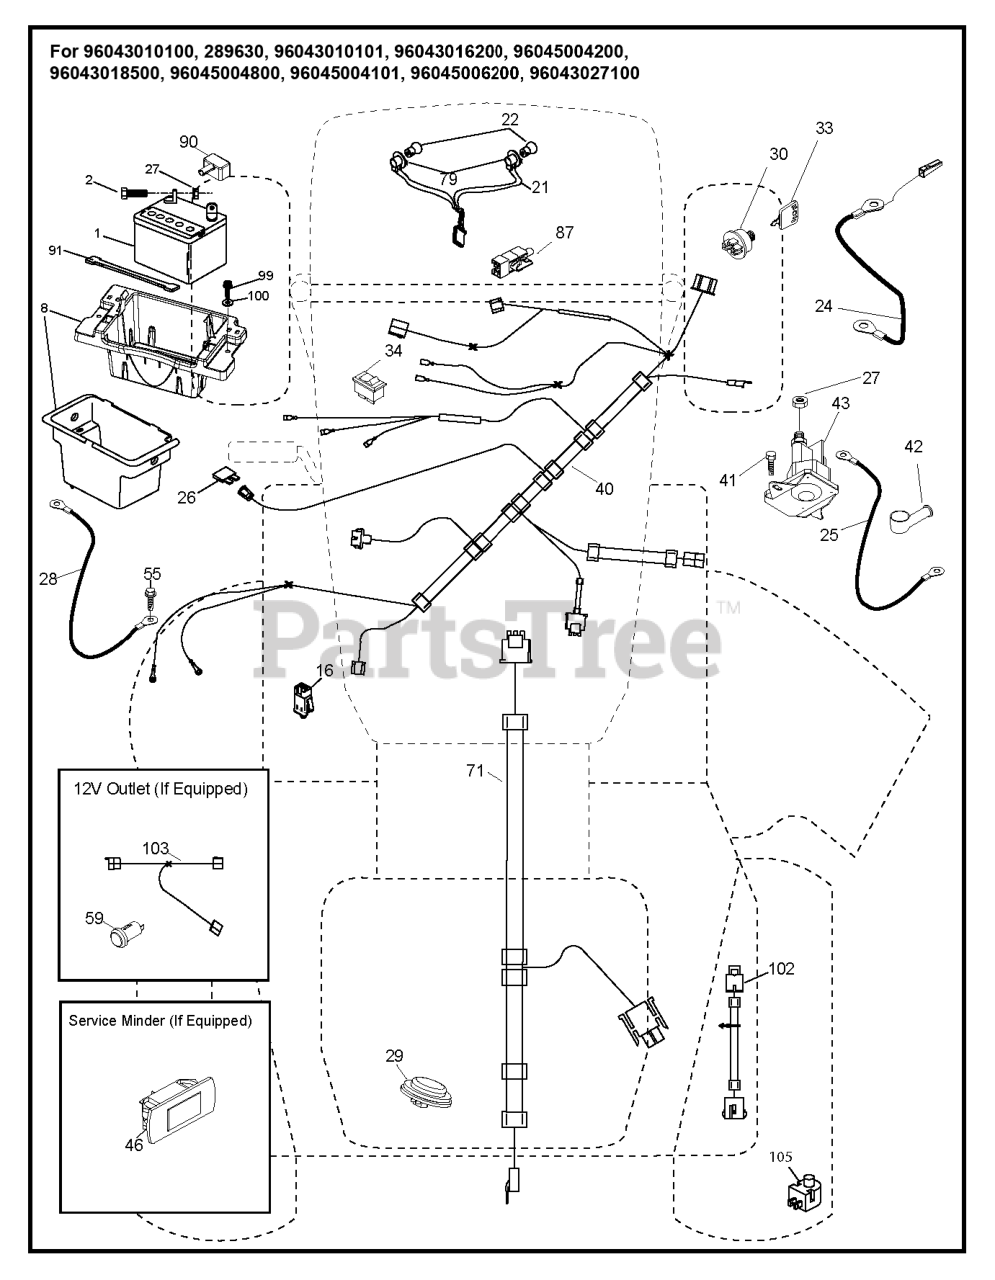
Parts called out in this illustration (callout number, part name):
1	Battery 12 Volt 25 Amp
2	BOLT.HEX.1/4.X.3/4.DICHROMATE
8	TRAY.BATTERY.FRNT.CARB W/SNAPS
8	TRAY.BATTERY BOX.FRONT
8	BOX.BATTERY.MNT.REAR.L
8	TRAY.ASM.BATTERY.FRT.TEX.CARB
16	SWITCH INTERLOOK PUSH-IN
21	HARNESS.LIGHT W/4152J BULBS
21	HARNESS ASSY LIGHT
24	CABLE.FRBATT.W/WIRE.8GA.8
25	CABLE.STARTER.8GA.17.5
26	FUSE 20AMP
27	Hardware
27	NUT
28	CABLE.GROUND.21"BLK.8GA.90T
28	CABLE GROUND 6 GA 21" 90T BLK
28	CABLE.BLACK.18"REAR.BA
29	SWITCH.SEAT.DELTA.OPC.
30	SWITCH.IGN.DELTA.W.LGH.ROS
33	KEY.CHAIN.BLISTER.PACK.GEN.USA
40	HARNESS.IGN.DASH.CBL.YTGT.PRED
40	HARNESS IGN. DASH
41	SCREW
42	TERMINAL COVER
43	Solenoids
43	SOLENOID.STARTER.BRASS.PLUNGER
46	GUAGE.SRVCMNDR.HRMTR.
55	SCREW 5/16"
71	HARNESS.IGN.CHASS.TEX.REAR.BAT
71	HARNESS-CHASSIS SUB
79	BULB HOLDER ASM.
87	SWITCH.INTRLCK.CLUTCH.
90	COVER.TERMINAL.BATTERY
91	STRAP.BATTERY.MOUNT.FRONT(2 2)
99	SCREW HEXWSHR 1/4-20X3/4
100	WASHER
100	Washers
102	HARNESS PIGTAIL PCH TEX ROS
105	REVERSE SWITCH
